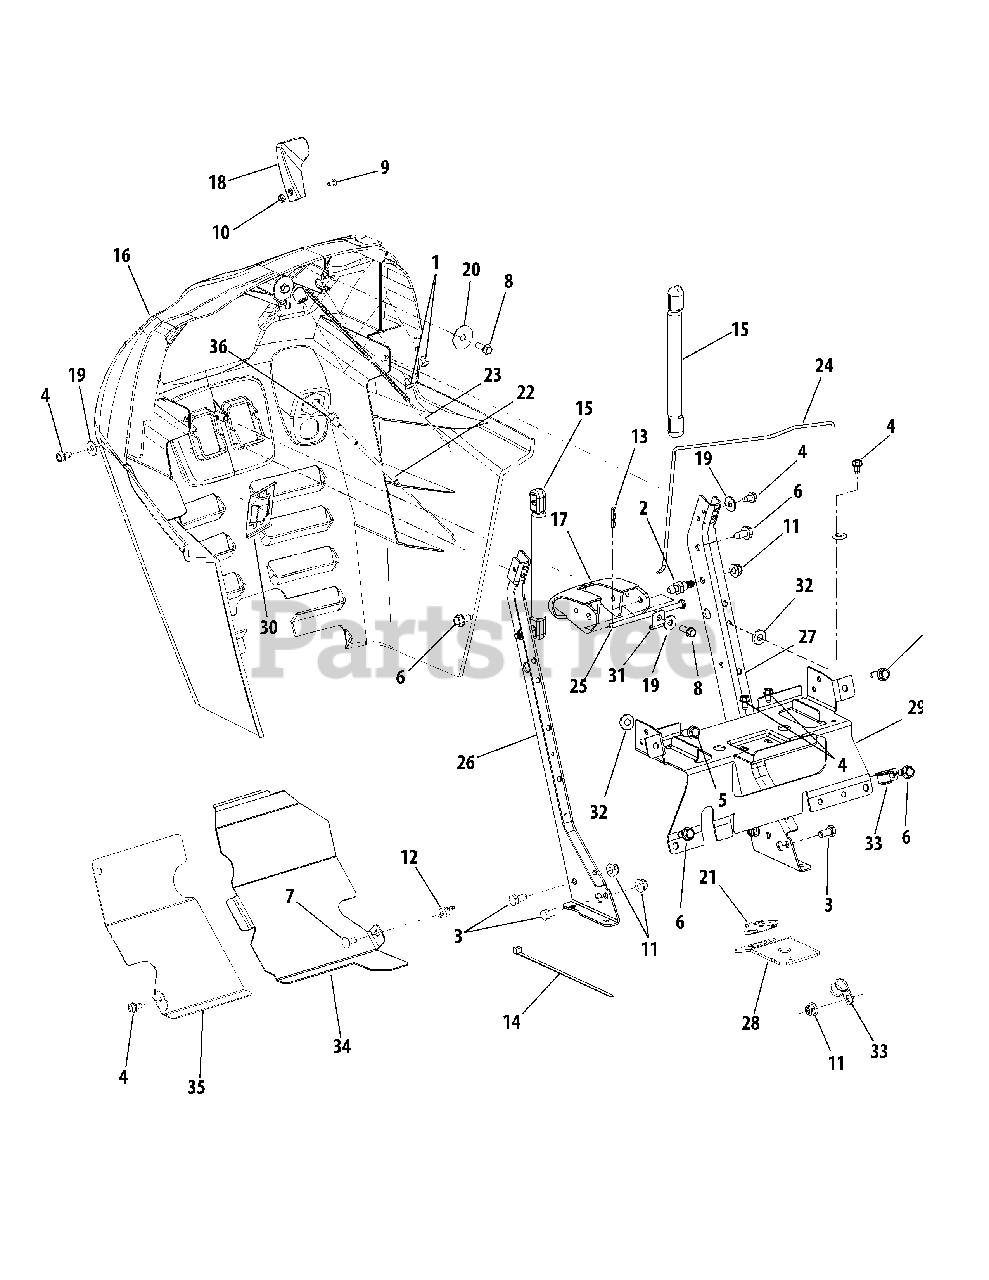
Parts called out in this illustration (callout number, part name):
1	Screw, #10-24 x .375
2	Screw, Ball Shoulder. 5/16-18 x .48
3	Screw, Hex Cap, 5/16-18 x .625 GR5
4	Screw, Self-tapping, 1/4-20, 0.500
5	Screw, Hx. Wash. Hd, Tapp. 5/16-18 x .875
6	Screw, Hx. Wash. Hd, Tapp, 5/16-12 x .75
7	Screw, Carriage, 1/4 -20 x .62
8	Screw, 1/4-15, 0.75
9	Screw, Truss Mach., #8-32 x .375
10	Nut, Hex, #8-32 GrA
11	Nut, Hx Insert Flange Lck, 5/16-18 GrF
12	Nut, Wing, 1/4-20
13	Internal Cotter Pin, .072 x 1.13
14	Tie, Cable
15	Cylinder, Gas
17	Lever, Dash, Cruise
18	Knob, Throttle Control
19	Washer, Flat, .28 x .74 x .063
20	Washer, Flat, .33 x 1.25 x .06 HT
21	Bushing, Steering Shaft
22	Cable, Choke
23	Cable, Throttle Control
24	Strap, Battery
25	Rod, .25 x 4.55
26	Plate, Dash Support RH
27	Plate, Dash Support, LH
28	Bracket, Steering Support
29	Bracket, Battery Support
30	Bracket, PTO Switch Retainer
31	Bracket, Rod, Dash
32	Washer, Flat, .344 x .75 x .12
33	Clamp, 9/16
34	Shield, Engine, LH
35	Shield, Engine, RH
36	Nut, Flange Lock, 3/8-16 Gr5
